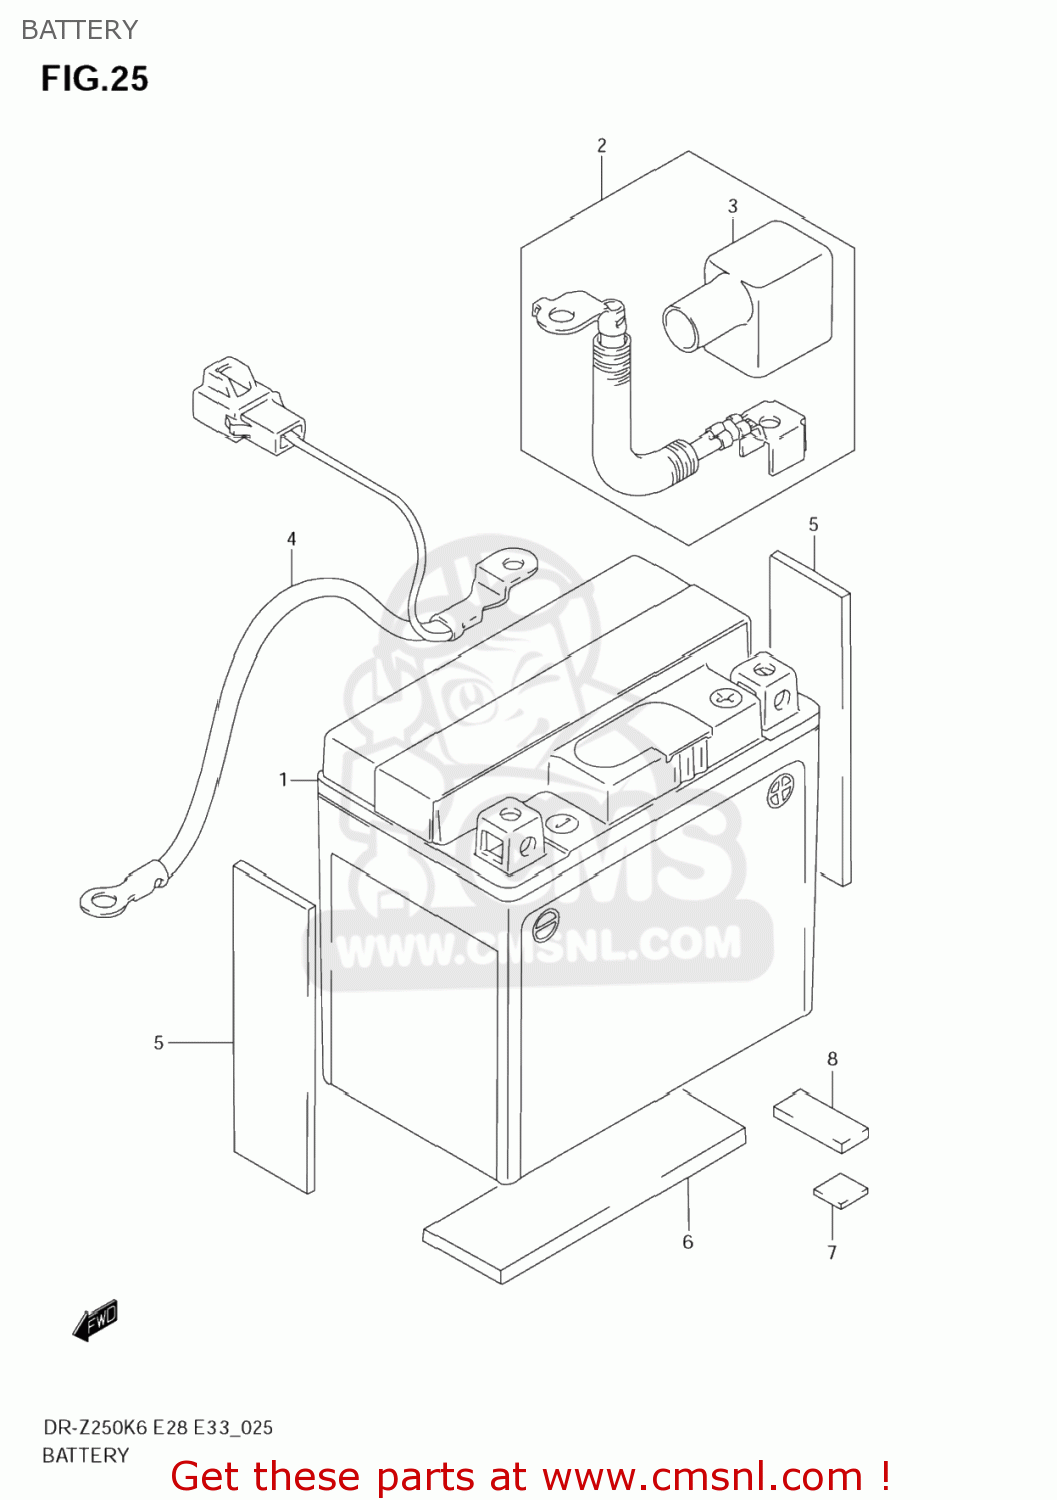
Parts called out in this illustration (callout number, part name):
1	BATTERY ASSY (FTZ5L-BS)
2	WIRE,BATTERY PLUS
3	CAP,BATTERY PLUS
4	WIRE,BATTERY MINUS
5	PROTECTOR(20X90)X1.0
6	PROTECTOR(170X95X3.0)
7	PROTECTOR(30X80X1)
8	PROTECTOR(80X80X2)
